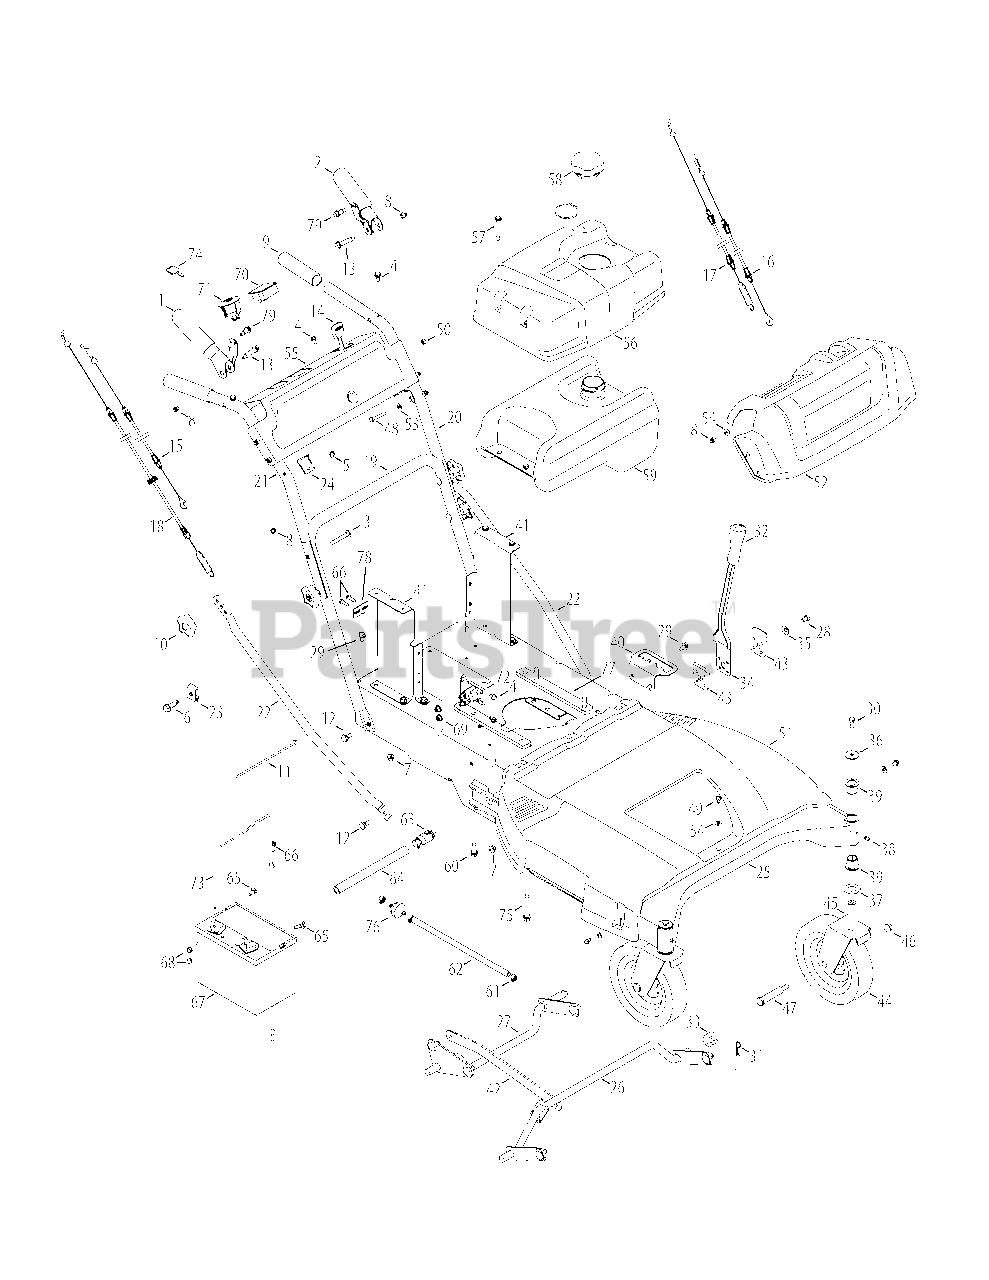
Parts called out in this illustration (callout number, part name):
1	RH Lever Assembly Bracket
2	LH Lever Assembly Bracket
3	Screw, Carriage, 5/16-18 x 2.25
4	Screw, 1/4-20 x 0.500
5	Hex Screw, 1/4-20 x 1.50
6	Screw, #10-32 x 0.625
7	Nut, Flangelock, 5/16-18
8	Lock Nut Cap, 1/4-20
9	Grip, 1.0 ID x 5.0 LG
10	Star Knob, 5/16-18
11	Cable Tie, 3/16 x .05 x 7.4
12	Screw, Shoulder, .435 x .178-5/16 x .56
13	Screw, Shoulder, .375 x 1.355 x 1/4-20
14	Throttle/Choke Cable, 38.0 x 1.1 EXT
15	RH Trans Brake Cable
16	LH Trans Brake Cable
17	Wheel Clutch Cable
18	Deck Clutch Cable
19	Lower Handle
20	Upper LH Handle
21	Upper RH Handle
22	Adjustable Handle Brace
23	Casing Clamp
24	RH Cable Mount Bracket
24	LH Cable Mount Bracket
25	Frame Assembly
26	Front Deck Lift Assembly
27	Rear Deck Lift Assembly
28	Hex Screw, 5/16-18 x .50
29	Screw, 5/16-18 x 0.625
30	Hex Screw, 5/16-24 x .750
31	Click Pin, .092 x 1.64 LG
32	Grip Handle, 1/2
33	Plastic Spacer, .63 ID x .75 LG
34	Deck Height Lever
35	Washer, Bell, .340 x .872 x .060
36	Washer, Flat, .330 x 1.25 x .120
37	Washer, Flat, .760 ID x 1.50 OD
38	Drive Lube Fitting, 3/16
39	Flange Bearing, .760 x .941 x 1.0
40	Height Adjustment Bracket
41	Fuel Tank Mount Bracket
42	Link Pivot Bracket
43	Lever Pivot Bracket
44	Caster, Wheel, 8 x 1.75
44	Bearing, Flange w/ftg
45	Wheel Caster Bracket
46	Nut, Flangelock, 3/8-16
47	Bolt, Shoulder, .625 x 2.515 x 3/8-16
48	Hex Screw, 1/4-20 x 1.75
49	Screw, 1/4-14 x 0.625
50	Nut, Hex, 1/4-20
51	Belt Cover
52	Handle Panel, Black
53	Washer, Bell, .265 x .75 x .062
54	Washer, Flat, .25 x .630 x .0515
55	Hour Meter and Key Handle Panel
56	Fuel Tank Cover
57	Screw, Shoulder, 1/4-20 x .32 x 1.8
58	Fuel Cap
59	Fuel Tank
60	Screw, 3/8-16 x 1.250
61	Hose Clamp, .490 DIA.
62	Fuel Hose, Low Permeation, 1/4
63	Oil Drain
64	Extension Hose
65	Hex Head Flange, 1/4-20 x .75
66	Screw, 1/4-20 x 0.750
67	Battery, 155 CCA WET
68	Sems Nut, 1/4-20
69	Nut, Flangelock, 1/4-20
70	Hour Meter
71	Key Switch
72	Solenoid, 12V, 100 Amp, 4 term
73	Battery Hold Down Strap
75	Screw, 3/8-16 x 2.25
76	Fuel Filter
77	Engine Mounting Plate
78	PLate, Shift
79	Screw, Shoulder, 1/4-28 x .342 x .335
